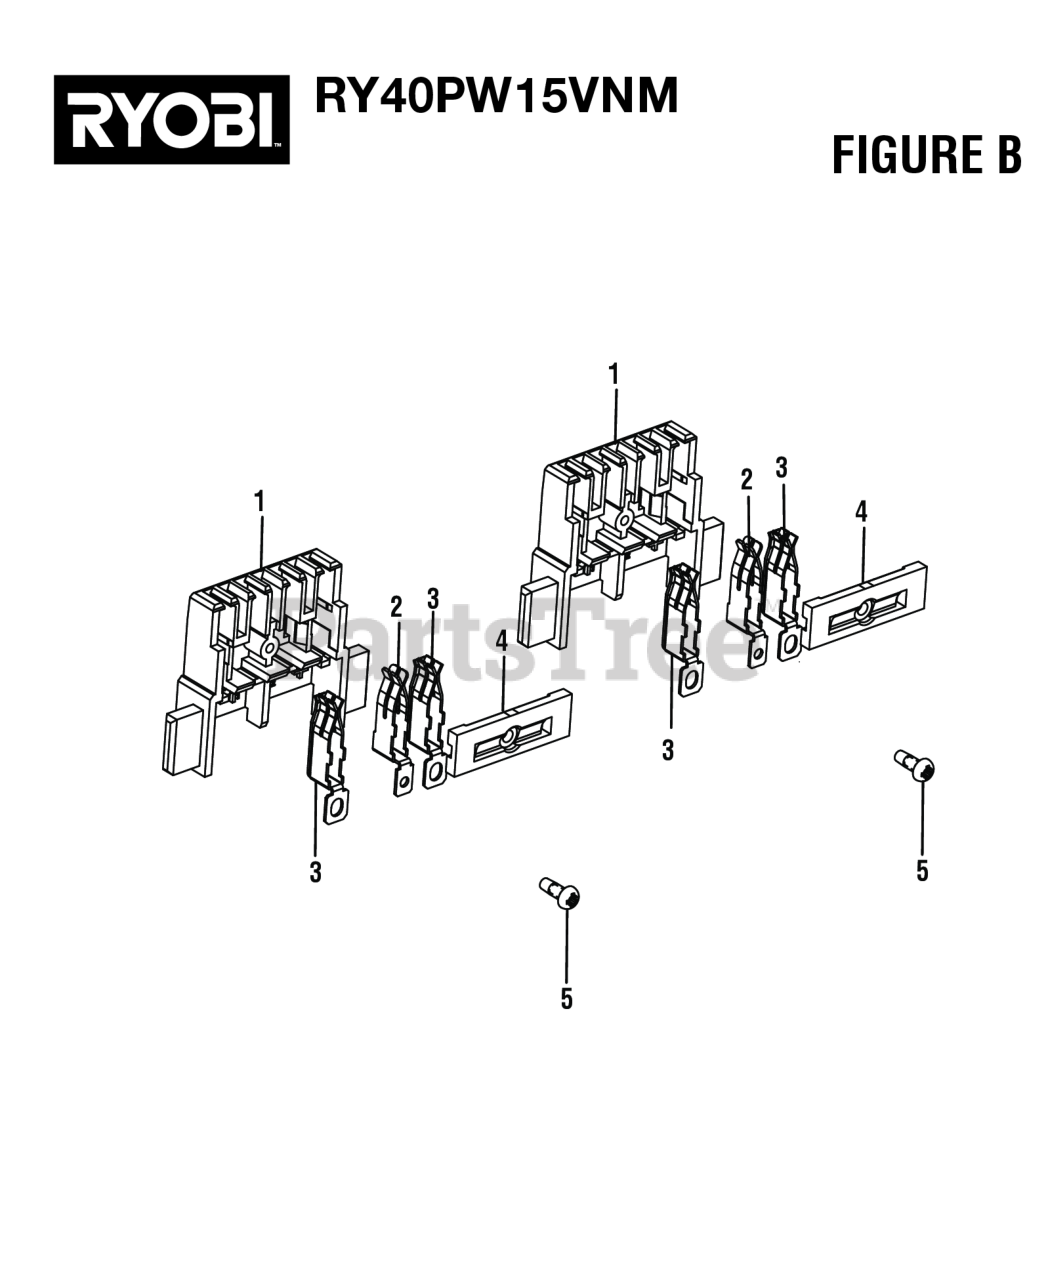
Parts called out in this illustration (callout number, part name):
1	Battery Contact Holder
2	STAMPING I BATTERY CONTACT PLATE TERMINA
3	Contact Plate Terminal
4	Battery Cover Connector
5	Screw (M3 x 8 mm, Pan Hd., Pan Hd)
